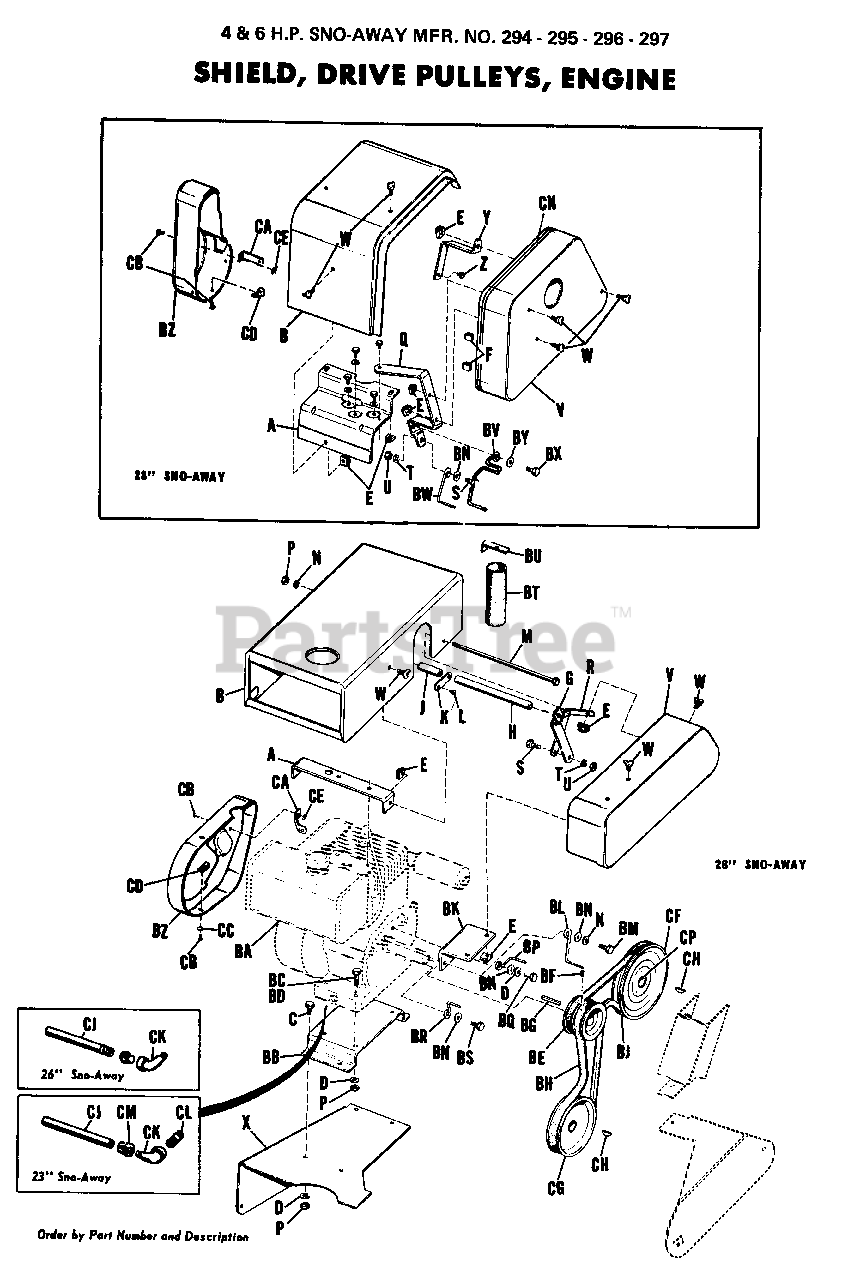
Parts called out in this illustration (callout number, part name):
A	Hood Support
B	Hood Assembly
E	Tinnerman Nut, #C31280-5618-1
F	Speed Clip
Q	Beat Guard Support
S	Hex Capscrew, 3/8"-16 x 7/8"
T	Lock Washer, 5/16"
U	Hex Nut, Full, 5/16"-18
V	Belt Guard Assembly
W	Thumb Screw
X	Side Cover, RH
Y	Belt Guard Bracket
Z	Screw,Rec. Hex. Hd., Self-Tapping, 1/4"-
BB	Engine Base
BD	Hex Capscrew, 5/16"-18 x 1-1/2" lg.
BE	Engine Pulley
BF	Set Screw, Cup Pt., Socket Hd., 5/16"-18
BG	Key
BH	V-Belt (Rotor Drive)
BJ	V-Belt (Transmission Drive)
BN	Plain Washer, 5/16"
BV	Belt Stop
BX	Hex Capscrew, 1/2"-20 x 1" lg.
BY	Lock Washer, Int. Shakeproof, 1/2"
BZ	Cover, Air Cooling
CA	Cover Bracket
CB	Screw, Self-Tapping #10 x 1/2" lg.
CD	Speed Nut, Special
CE	Speed Nut
CF	Pulley, Transmission Drive
CH	Key, Woodruff
CJ	Tube, Oil Filler
CK	Street Elbow, 90ø
CN	Strip, White
CP	Screw, Set
